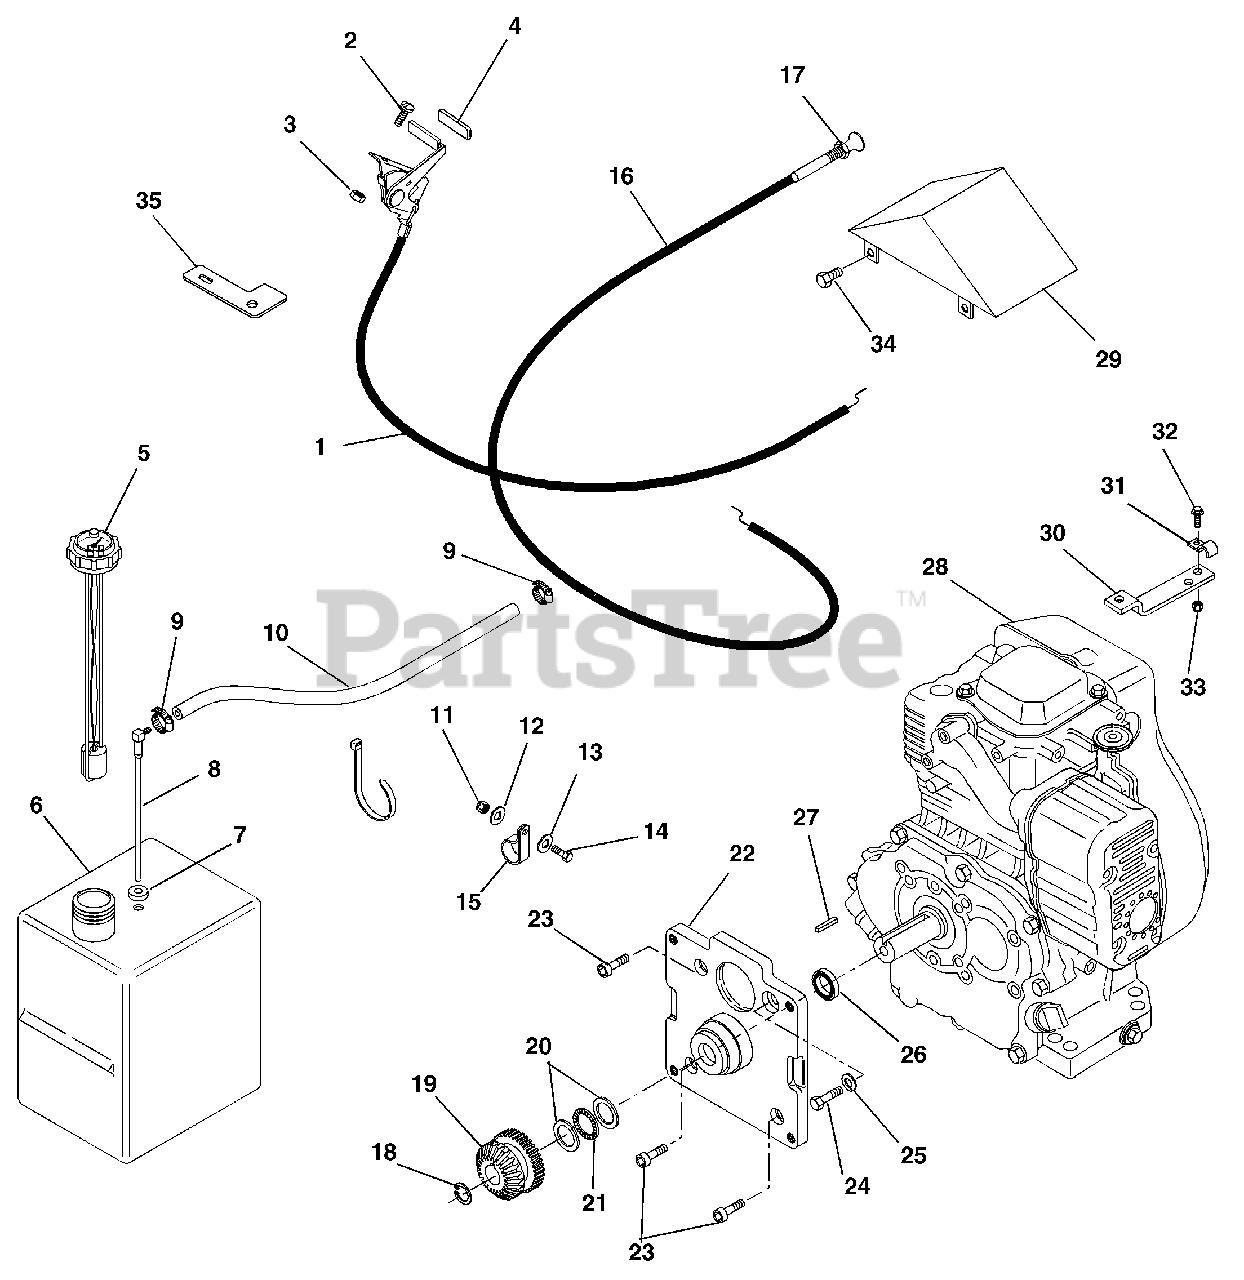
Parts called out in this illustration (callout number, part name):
1	Cable, Throttle Control
2	Screw-Machine 10-24 x .50 Hex Washer Head
3	Nut-Locking-Nylon 10-24 with Insert
5	Gauge, Fuel
6	Tank, Fuel
7	Bushing
8	Fitting, Tank
9	Clamp, Hose
10	Gas Line-Bulk 1/4" I.D.
11	Cable Tie
12	Nut-Locking-Center .31-18
13	Washer-Flat-Steel .34 x .69 x .065
14	Bolt-Hex .31-18 x 1.00 Grade 5
15	Cable Clamp
16	Cable, Choke Control
17	Nut-Jam .38-24
18	Ring-Retaining 1.25 x .05
19	Gear, Spur and Bevel (Input)
20	Washer-Thrust 1.13 x 1.75 x .12
21	Bearing-Needle-Thrust 1.84 x 1.13 x .078
22	Adapter, Engine
23	Bolt-Hex .38-16 x 1.00 Grade 5
24	Screw-Socket Head .44-14 x 1.00
25	Bolt Hex .31-24 x 1.00 Grade 5
26	Seal 1.989 x 1.38 x .31
27	Key-Square .25 x 1.25 x .25
28	Engine, Robin
29	Panel, Linkage Cover
30	Bracket, Cable
32	Screw-Machine 6-32 x 1.00
33	Nut-Locking-Nylon 10-24 with Insert
34	Bolt-Hex M8 x 1.25 x 16
35	Stop, Throttle Cable
